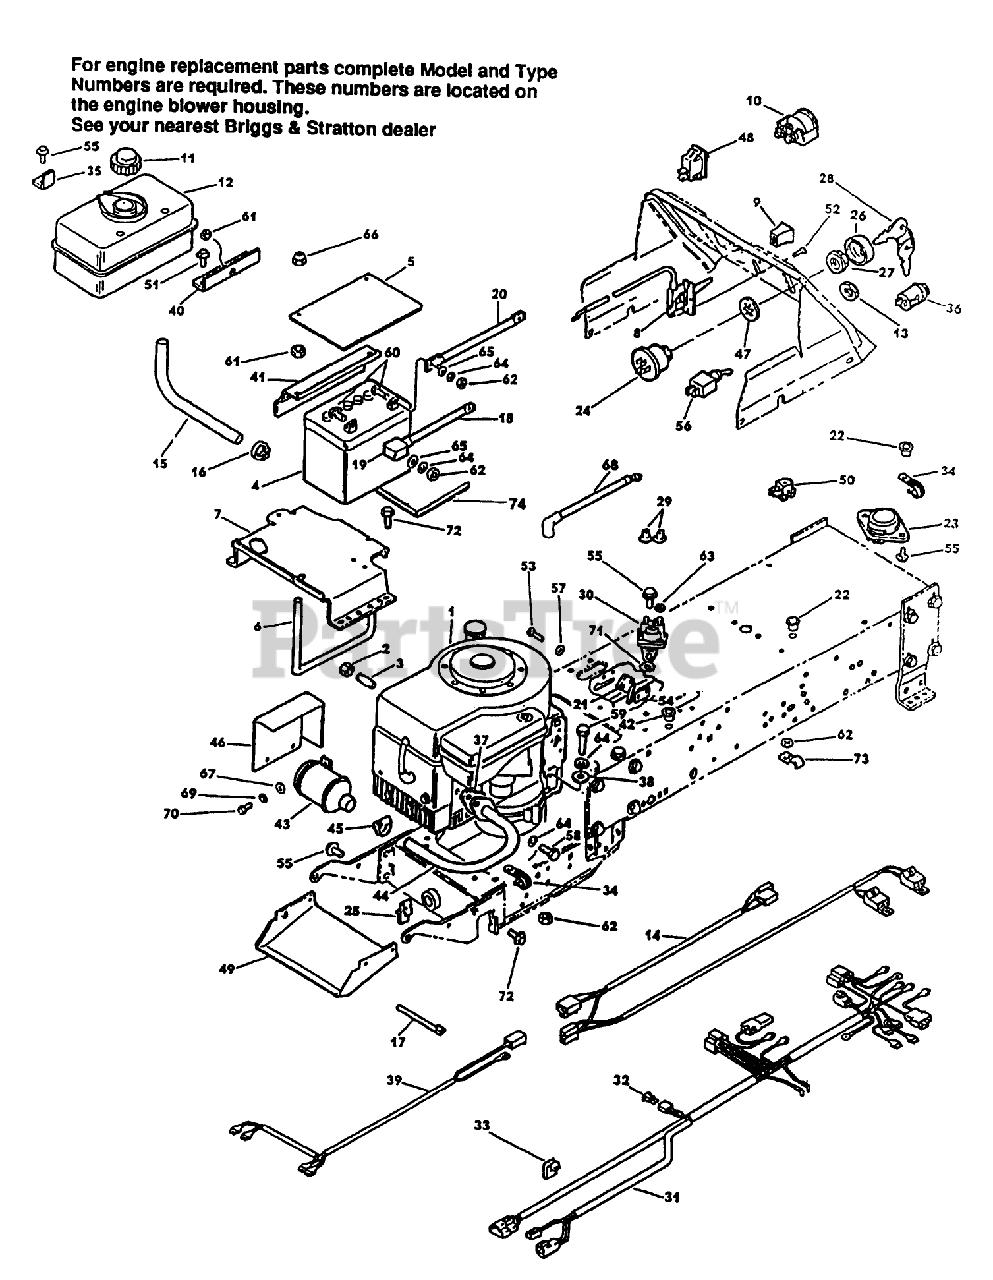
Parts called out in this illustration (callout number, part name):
1	Engine-10.5 H.P. B S
9	THROTTLE KNOB
11	CAP-FUEL
12	TANK & STICKER AY
18	CABLE ASSEMBLY
21	SWITCH-SEALED
23	SWITCH,SEAT
25	CLIP-RETAINER, WIRE
30	SOLENOID
36	LIGHT-PTO INDICTOR
48	SWITCH ASSEMBLY
56	SWITCH-PTO W/SAFTY
60	SCREW - HEX
63	NUT-HEX
66	NUT-LOCK, CONE
